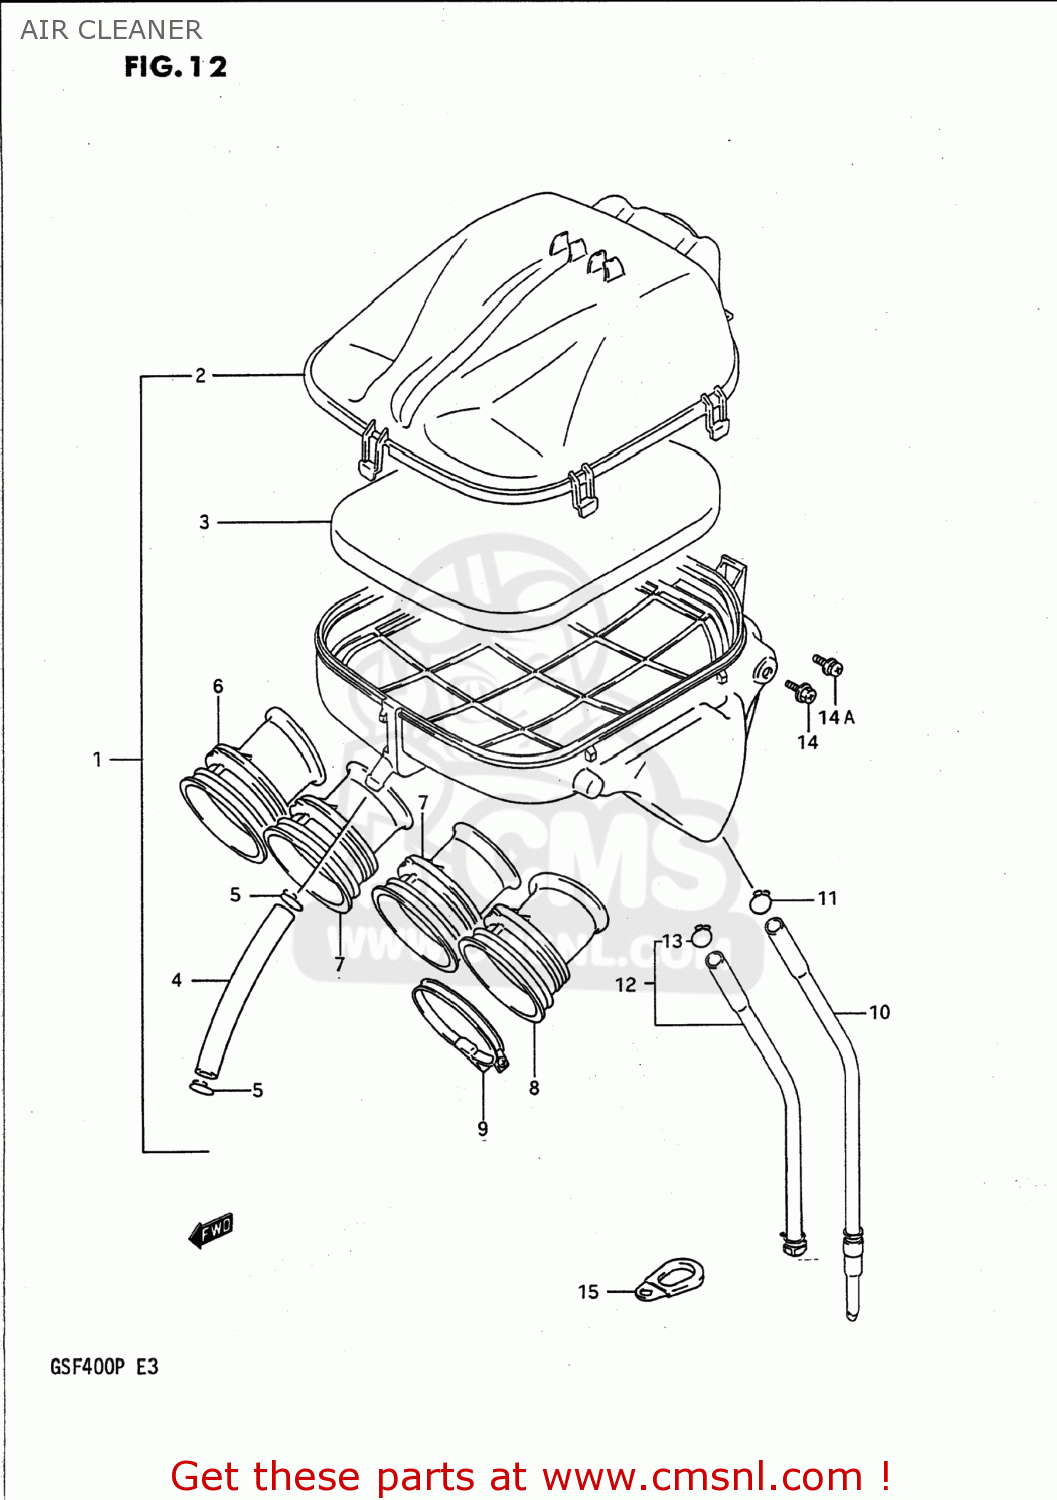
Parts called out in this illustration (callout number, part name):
1	CLEANER ASSEMBLY,AIR
2	CAP,AIR CLEANER
3	ELEMENT,AIR CLEANER
4	TUBE,BREATHER
5	CLIP
6	TUBE,OUTLET NO.1
7	TUBE,OUTLET NO.2
8	TUBE,OUTLET NO.4
9	CLAMP
10	DRAIN TUBE
11	CLIP
12	DRAIN TUBE
13	CLIP
14	BOLT 6X16
14A	SCREW
15	PLATE,DRAIN TUBE GUIDE
